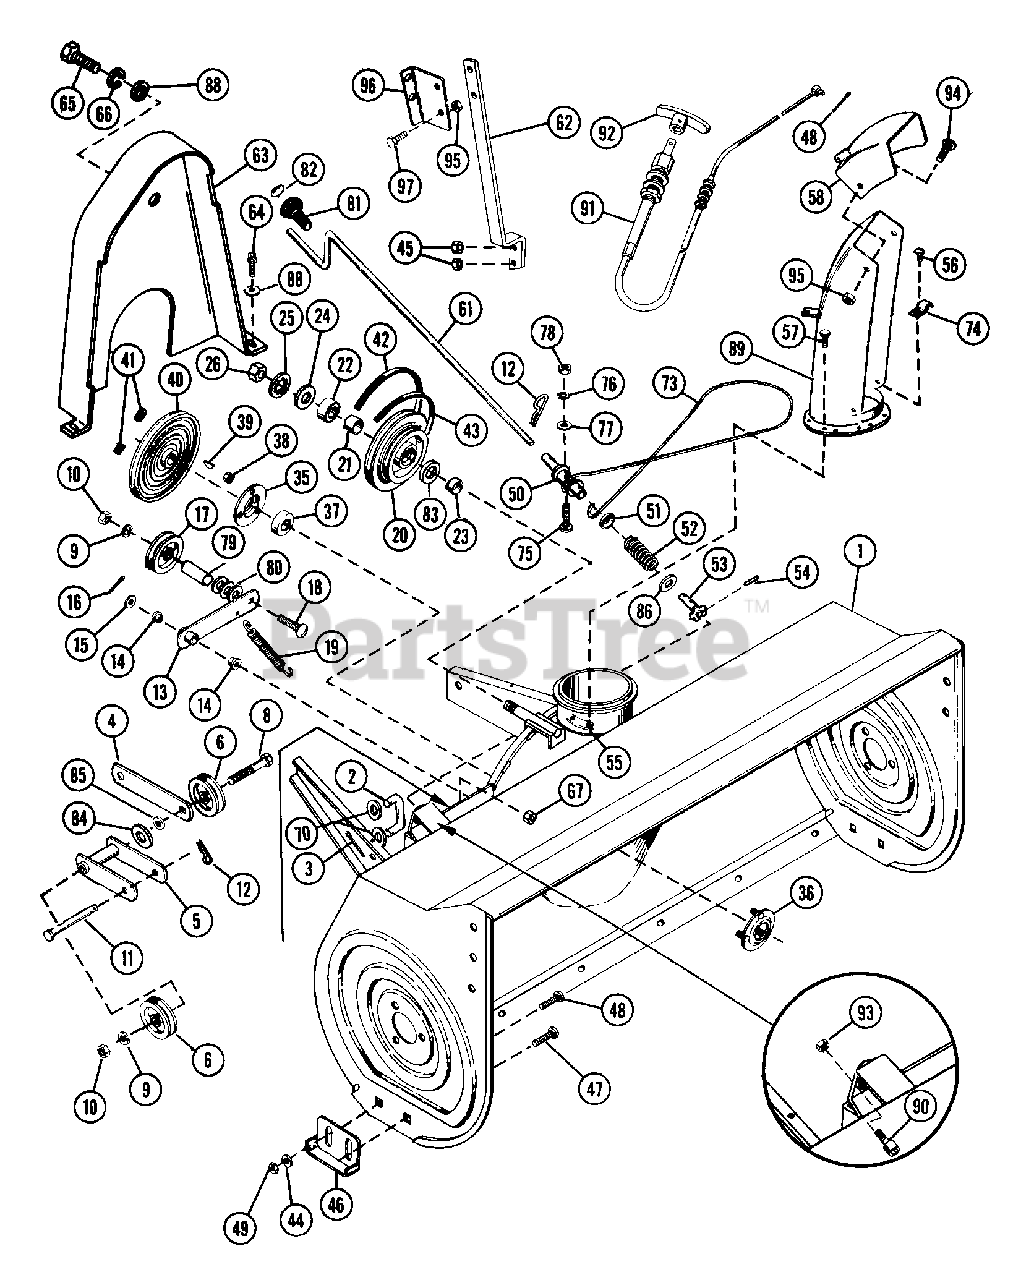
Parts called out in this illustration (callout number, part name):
1	36 IN SNO THRO HOUSING WITH DE
2	LIFT LINK
3	PIN-COTR .12X1.0 PL
4	STRAP
5	IDLER BRACKET
6	IDLER-V 4.00 X .38 NWHAMSHR
7	WSHR-FL-STL.656X1.312X.095 PL
8	BLT-HEX .38-16X5.00 PL GR2
9	WSHR-LK .375X.115 HVY PL
10	NUT-HEX .375-16
11	CLEVIS PIN 3/8X3.0 YWZC
12	PIN-HAIR INT .08X.38X1.42 YWZC
13	IDLER ARM
14	BSHG-FLG .372X.500X.312X.625NY
15	WSHR-FL-STL .382X.812X.062
16	PIN-COTR .12X.75 PL
17	IDLER
18	BLT-RDHDSQNK .38-16X1.75 PL
19	SG-TENS .090X.75X3.50 WLD 34
21	SPACER 1.00 X .770/.760 X .813
22	BRG-BALL .750X1.781X.61
23	SPACER 1.00 X .770/.760 X .375
24	WSHR-FL-STL .781X1.250X.059 PL
25	WSHR-LK-INT .750X.050 MED
26	NUT-JAM .75-10 PL
35	BEARING FLANGE
36	BEARING FLANGE
37	BRG-BALL 1.0X2.0X.56
38	NUT-LK-CTR .250-20 PL
39	BSHG-SLV 1.625X2.000X1.500
40	PLY-V 7.50 X .75 W/KEY SALEM
41	SCR-SET .32-18X.50 SKHCUP OH
42	V-BELT, HA-WRAPPED
44	WSHR-FL-STL .38X.875X.083 PL
45	NUT-LK .312-18 GR A PL
46	SKID SHOE
47	BLT-RDHDSQSHNK .38-16X1.00 PL
48	BLT-RDHDSQNK .38-16X.75 SHT PL
49	NUT-LK-CTR .375-16 GR A PL
51	SPHERICAL WASHER
52	SG-COMP .054X.75X1.6
53	DISC ASSEMBLY
54	PIN-ROLL .188X1.00
55	CHUTE CLAMP
56	SCR-TAP 10-24X.375 CRPH PL 1A
57	SCR-TAP 10-24X.75 CRPH 1A
58	DEFLECTOR W/DECAL
59	BLT-HEX .38-16X.75 PL GR2
60	WING NUT
61	CHUTE CRANK
62	CHUTE CRANK SUPPORT
63	BELT GUARD
64	BLT-SERHFWH .31-18X.50 PL
65	BLT-HEX .31-18X.75 PL GR5
66	WSHR-LK .312X.097 PL HVY
67	NUT-HEX .312-18
70	WSHR-FL-STL.656X1.312X.095 PL
74	CABLE CLAMP
75	BLT-RDHDSQNK .25-20X.62 PL
76	WSHR-LK .313X.062
77	WSHR-FL-STL.281X.62X.065 PL
78	NUT-HEX .250-20 PL
79	SPACER -FLANGED .390X.500X.781
80	WSHR-FL-STL .438X1.0X.083 PL
82	CAP, 3/8 ROD YWZC
83	WSHR-FL-STL .781X1.500X.188
84	WSHR-FL-STL .755X1.375X.062 PL
85	WSHR-FL-STL .382X.812X.062
86	WSHR-FL-STL .633X1.000X050
87	PIN-HAIR INT .09X.188 PL
88	WSHR-FL-STL .38X.875X.083 PL
89	DISCHARGE CHUTE
90	SCR-SKH 10-24X.38
91	CHUTE CONTROL
92	T-HANDLE
93	NUT-LK DUAL FACE 10-24 PL
94	BLT-HEX .38-16X.75 PL GR2
95	NUT-LK-CTR .375-16 GR A PL
96	CONTROL BRACKET
97	BLT-HEX .38-16X1.00 PL
